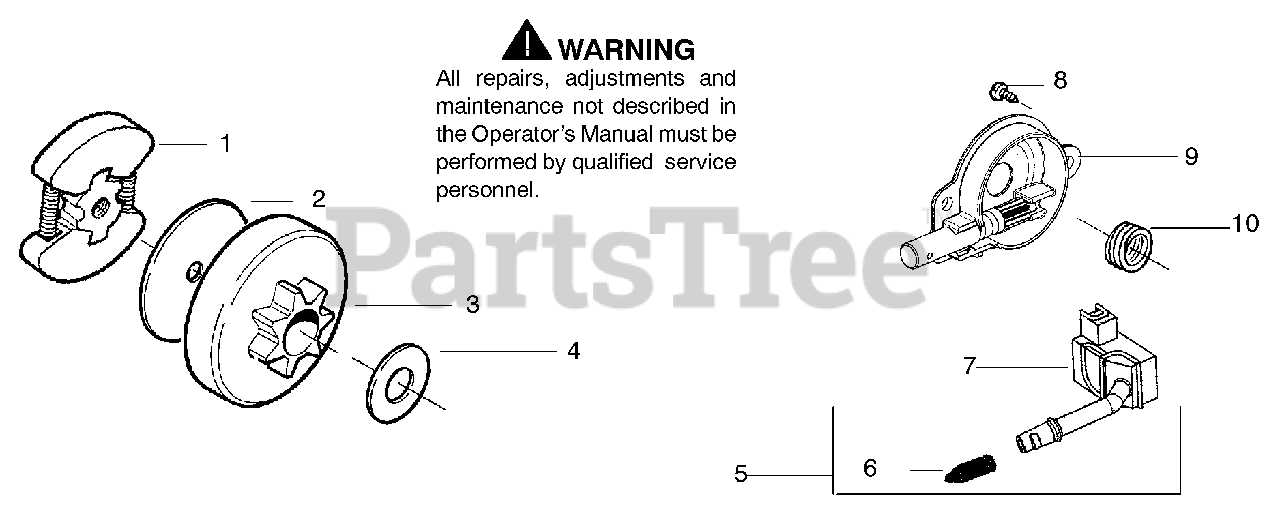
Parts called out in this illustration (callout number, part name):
1	Assy-Clutch
2	Washer-Clutch
3	Assy-Clutch Drum w/Bearing
4	Washer-Thrust
5	Assy-Oil pickup and screen
6	Filter-Oil
7	Assy-Pickup
9	Assy-Oil Pump
10	Worm Gear-Oil Pump
